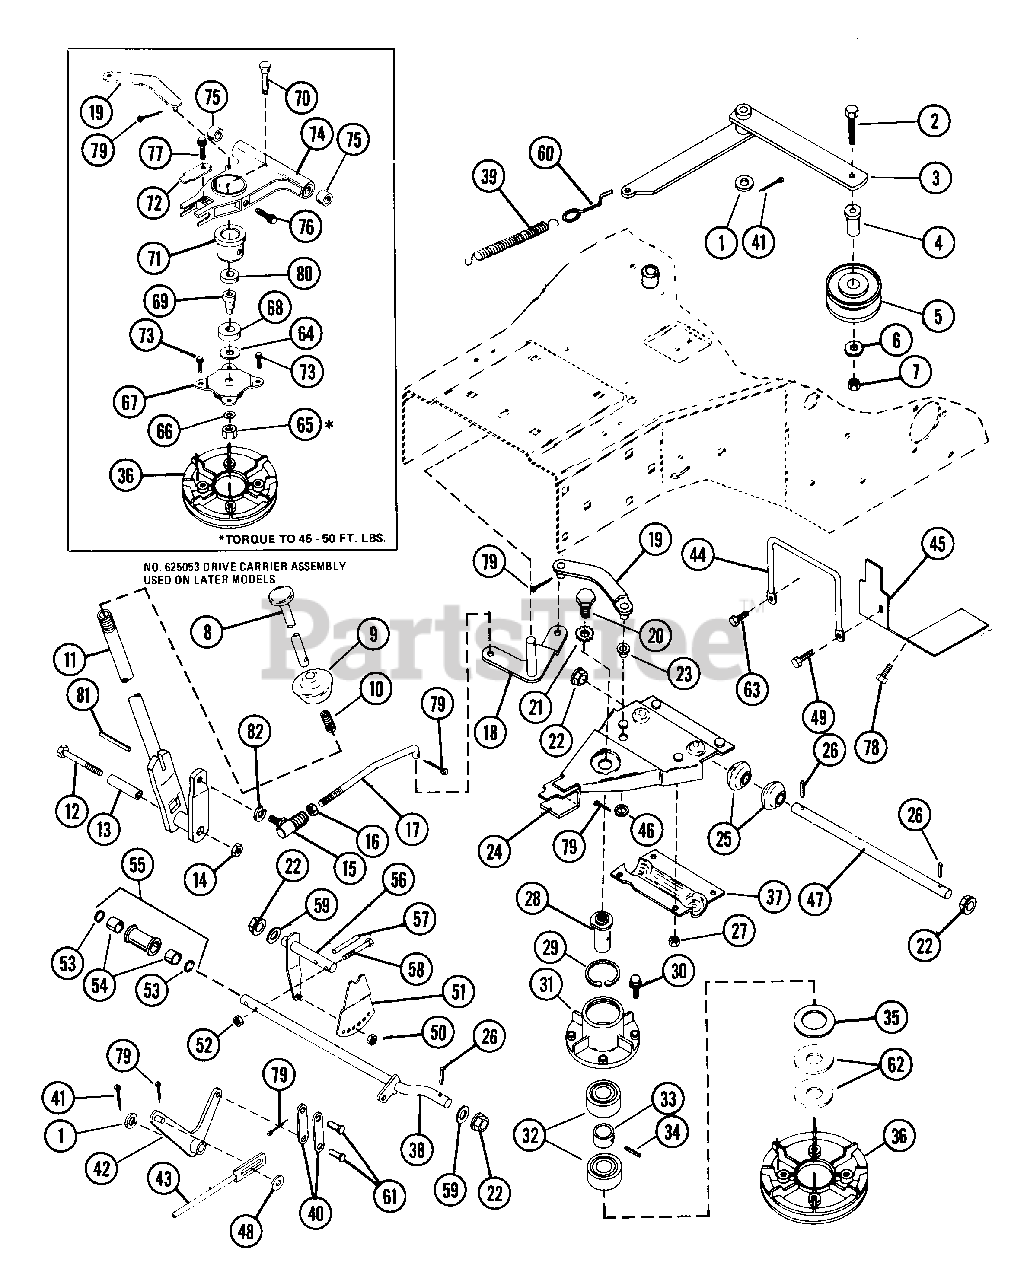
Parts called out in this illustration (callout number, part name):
1	WSHR-FL-STL .505X1.000X.062
2	BLT-HEX .31-18X1.25 PL GR2
4	SPCR, BRG .315X.50X.688X.281
5	IDLER
6	WSHR-FL-STL .38X.875X.083 PL
7	NUT-LK .312-18 GR A PL
8	SHIFT CONTROL ROD
9	SHIFT BALL
10	SG-COMP ??X.44X?? WLD 10
11	SHIFT LEVER
12	BLT-HEX .38-16X2.50 PL GR2
13	SHIFT SPACER
14	NUT-LK-CTR .375-16 GR A PL
15	SNAP IN BALL JOINT
16	NUT-HEX .312-24 PL
17	SHIFT ROD
18	SHIFT LEVER
19	SHIFT LINK
20	SPINDLE STUD
21	WSHR-LK-EXT .500X.040 MED
22	FLANGE BUSHING
23	BSHG-FLG .372X.500X.312X.625NY
24	MTG PLATE
25	BEARING
26	PIN-ROLL .188X1.13
27	NUT-LK-CTR .250-20 PL
28	SPINDLE
29	SNAP RING KIT
30	BLT-SERHFWH .25-20X.75 PL
31	SPINDLE HOUSING
32	BRG-BALL .751X1.78X.61
33	SPACER .753X1.000X.457
34	PIN-ROLL .188X1.00
35	WSHR-FL-STL 1.375X2.125X.075
37	BEARING RETAINER
39	SG-TENS 5.65 FREE LENGTH
40	LINK PLATE
41	PIN-COTR .09X1.0 PL
42	CLUTCH LEVER
43	CLUTCH ROD
44	BELT GUIDE
45	SPLASH GUARD
46	WSHR-FL-STL .505X.880X.072 PL
47	HINGE SHAFT
48	WSHR-FL-STL .382X.812X.023 PL
49	BLT-HEX .25-20X.75 PL GR2
50	NUT-KEPS 8-32
51	STOP ADJUSTMENT
52	NUT-LK TOP .250-20 PL
53	SEAL .625X.875X.125
54	BSHG-SLV .625X.750X.500 BR
55	ROLLER ASSEMBLY
57	PIN-GRV .250X1.25 TP A
58	BLT-HEX .25-20X1.50
59	WSHR-FL-STL .630X1.005X.062 PL
60	SPRING HOOK
61	CLEVIS PIN
62	WSHR-FL-STL 2.125X1.375X.005
63	BLT-HEX .25-20X.75 PL GR2
64	WSHR-HDND-THRST .758X1.23X.031
65	NUT-LK-CTR .50-20 PL
66	WSHR-HDND-STL-THR.515X.97X.062
67	DISC ADAPTER
68	BRG-BALL .750X1.781X.61
69	SHOULDER SPACER
70	SPINDLE BOLT
71	BEARING HOUSING
72	NEUTRAL TAB
73	BLT-SERHFWH .25-20X.50 PL
74	DRIVE DISC CARRIER
75	BSHG-SLV .625X.750X.500 BR
76	BLT-SERHFWH .31-18X.50 PL
77	BLT-SERHFWH .31-18X.75 PL
78	BLT-HEX .25-20X.50 PL GR2
79	PIN-COTR .09X.75 PL
80	BRG-BALL .625X1.375X.44
81	PIN-ROLL .188X1.50
82	WSHR-LK-EXT .375X.050
